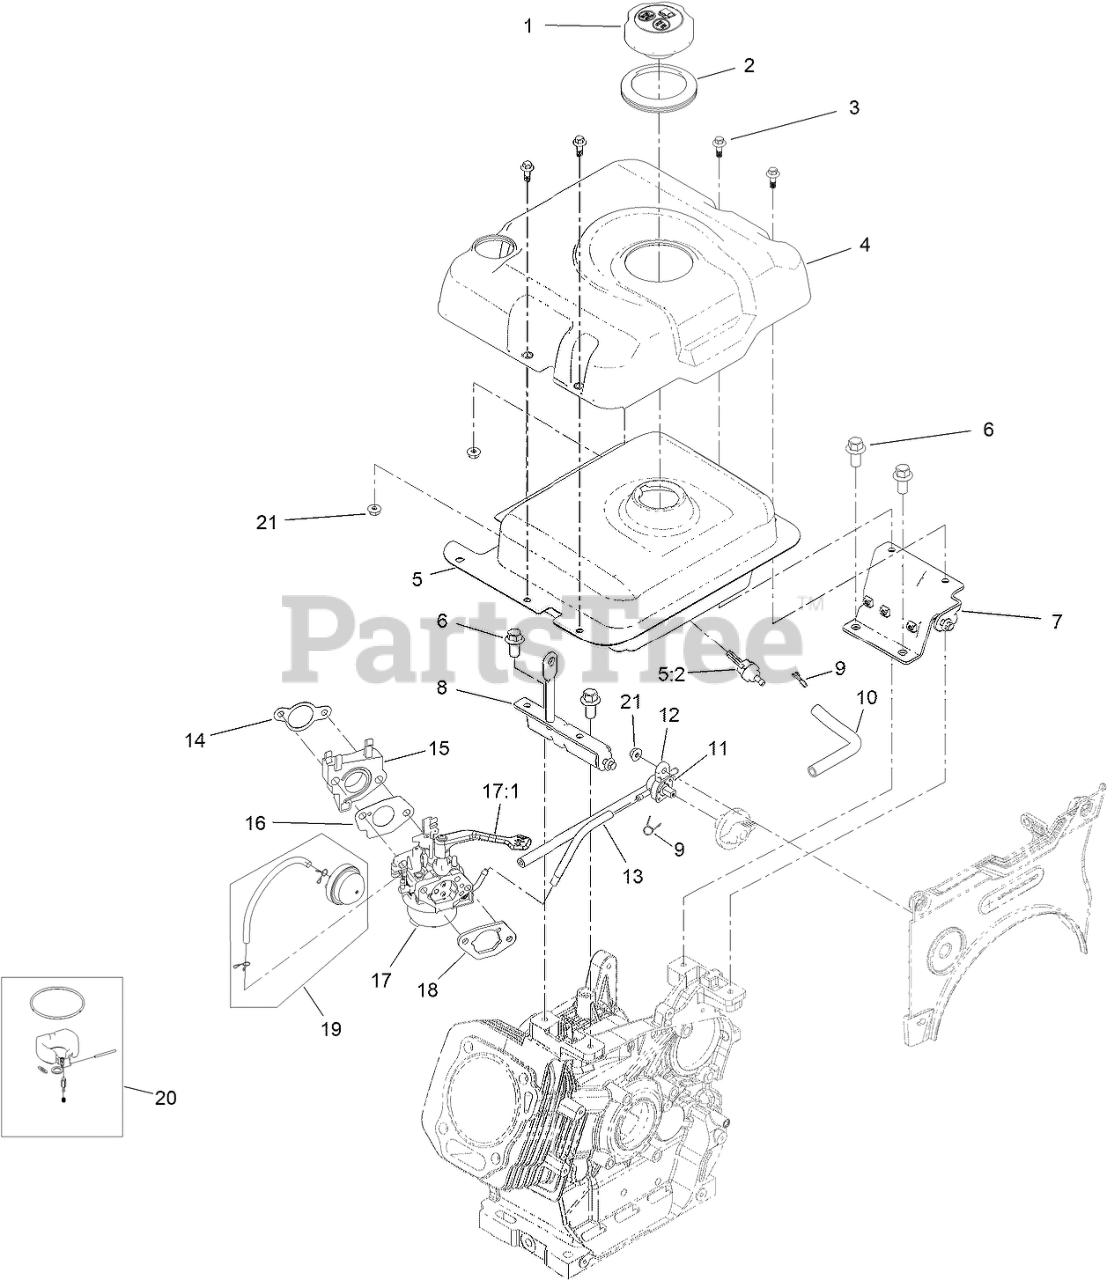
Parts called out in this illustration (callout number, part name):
1	CAP-FUEL
2	INSERT-COVER, TANK
3	SCREW-HHF
4	COVER-TANK, FUEL
5	FUEL TANK AND FILTER ASM
5:2	FILTER-FUEL
6	SCREW-HHF
7	BRACKET-TANK, RIGHT
8	BRACKET-TANK, LEFT
9	CLIP-HOSE
10	SLEEVE-ABRASION
11	HOSE-FUEL
12	VALVE-FUEL
13	HOSE-FUEL
14	GASKET-CARBURETOR
15	INSULATOR-CARBURETOR
16	GASKET-CARBURETOR
17	CARBURETOR ASM
17:1	LEVER-CHOKE
18	GASKET-COATED, RUBBER
19	PRIMER KIT
20	INTERNAL CARB SERVICE KIT
21	NUT-FLANGE
